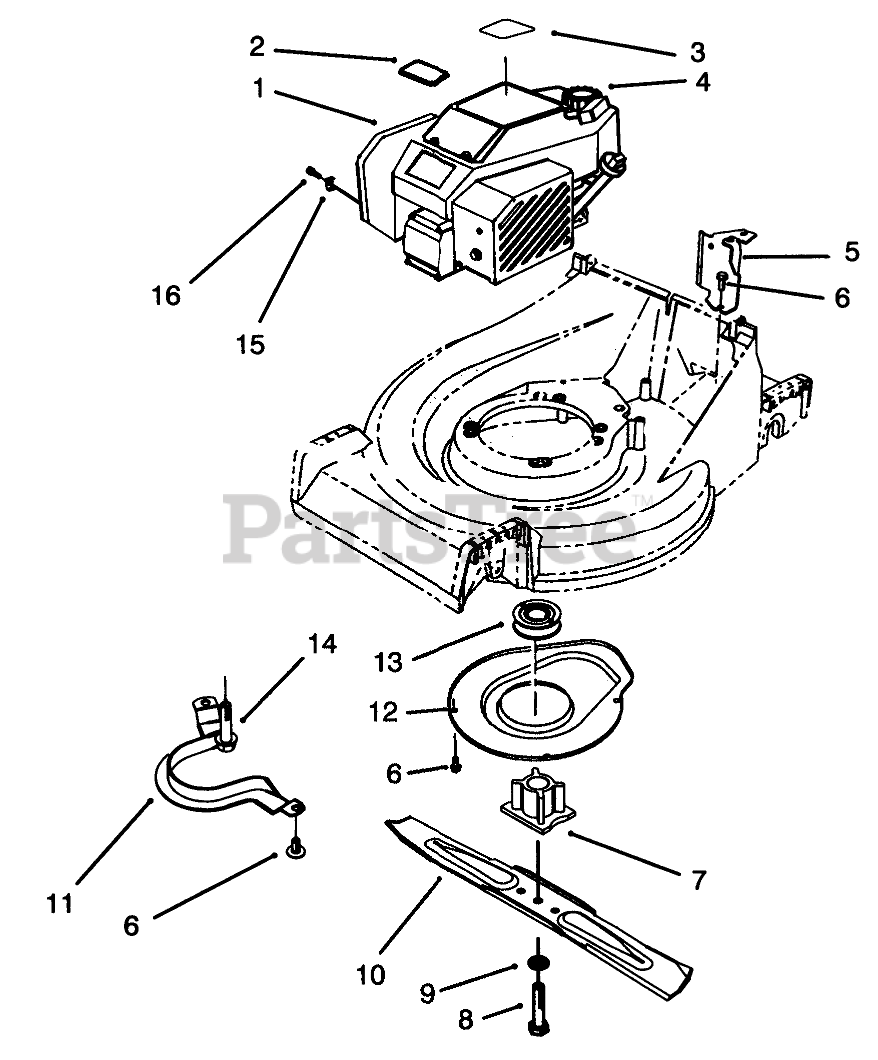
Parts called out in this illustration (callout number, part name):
1	ENG ASM-GTS150 KEY/NC
2	PLATE-LOGO
3	DECAL - ENGINE
4	GAS CAP ASM
5	Bracket-Cable Support
6	SCREW-HWHTF
7	BLADE RETAINER
8	SCREW-BLADE
9	WASHER-LOCK
10	Key
11	Guide-Belt
12	Cover
13	PULLEY-DRIVE, ZONE START
14	SCREW-HWH
15	CLAMP-CASING
16	CLAMP SCREW F/W ENGINE
